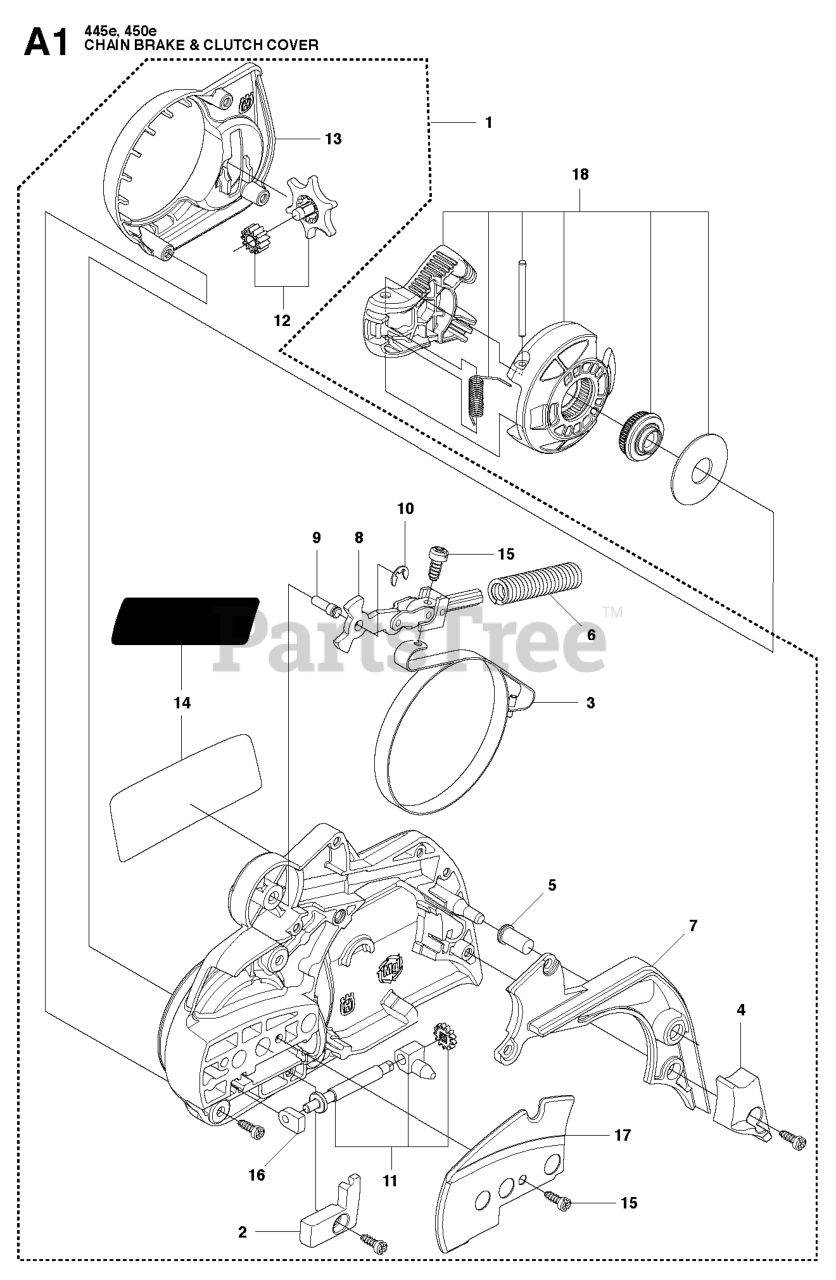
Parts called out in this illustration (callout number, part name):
1	CLUTCH HOUSING COMPLETE
3	BRAKE BAND
4	WEAR GUARD, CHAIN
7	COVER, CHAIN BRAKE
11	CHAIN TENSIONER SCREW, COMP.
12	CHAIN TENSIONER WHEEL, COMP.
13	HEAT SHIELD
14	DECAL, CLUTCH HOUSING
16	BEARING SLEEVE
18	KNOB, COMPLETE
